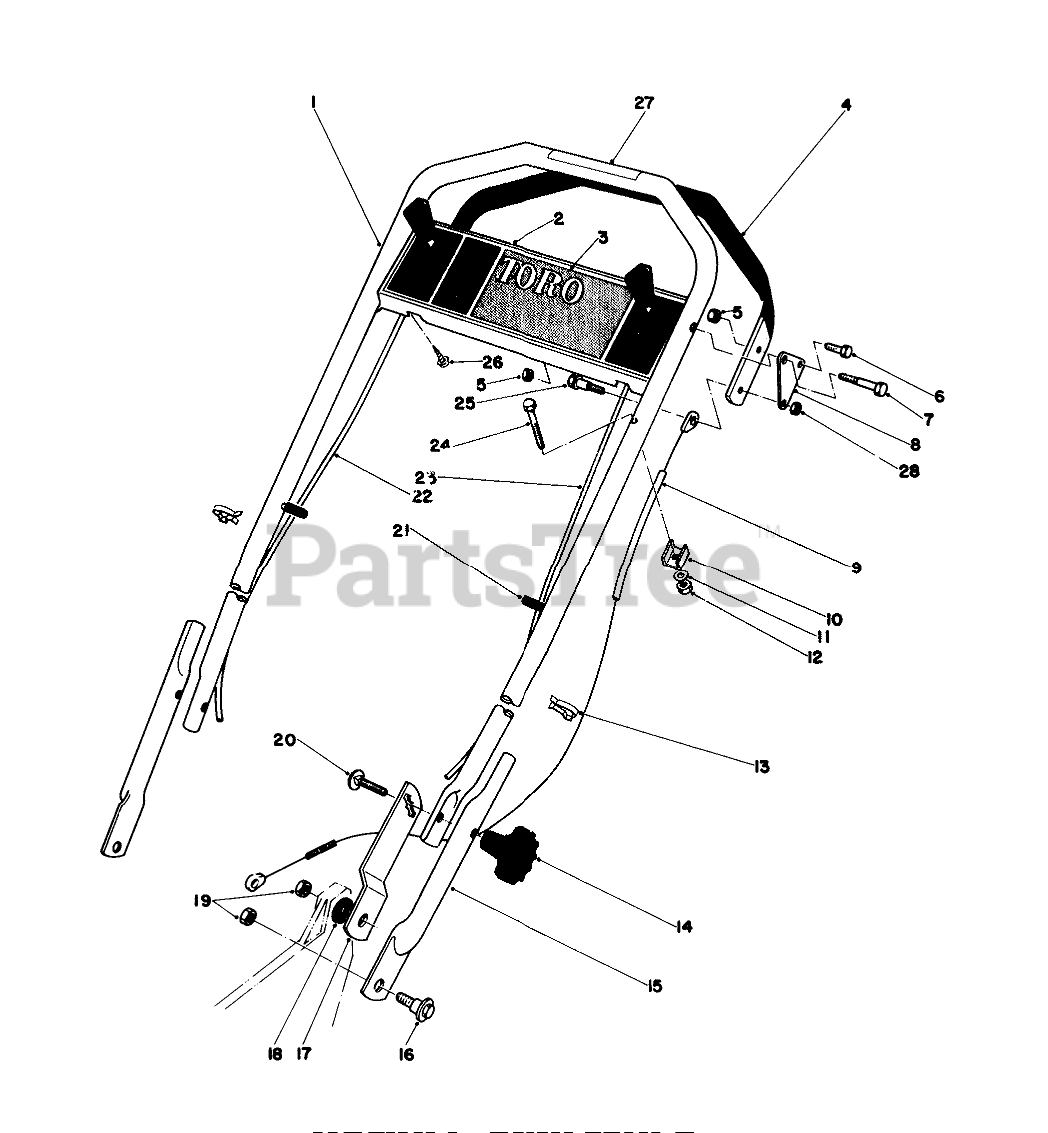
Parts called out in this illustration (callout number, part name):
1	Upper Handle
2	Control Plate
3	Decal-Control Panel
4	DEMAND HANDLE ASM
5	NUT-LOCK, CONE
6	SCREW-HH
7	BOLT-SHOULDER
8	Bracket Demand
9	DEMAND HAND CABLE
10	CLAMP-CABLE
11	WASHER-FLAT
12	NUT-LOCK, NI
13	BOWDEN CLIP
15	LOWER HANDLE
16	SCREW-SHOULDER
17	Handle Latch L.H.
18	SPACER
19	Nut
20	SCREW-CARR
21	CAP-VINYL
22	Ground Speed Control
23	Throttle Control
24	SCREW-HH
25	Shoulder Bolt
26	SCREW-HWHTF
27	Decal-Danger
28	NUT-HEX, SIDE DEFORM
